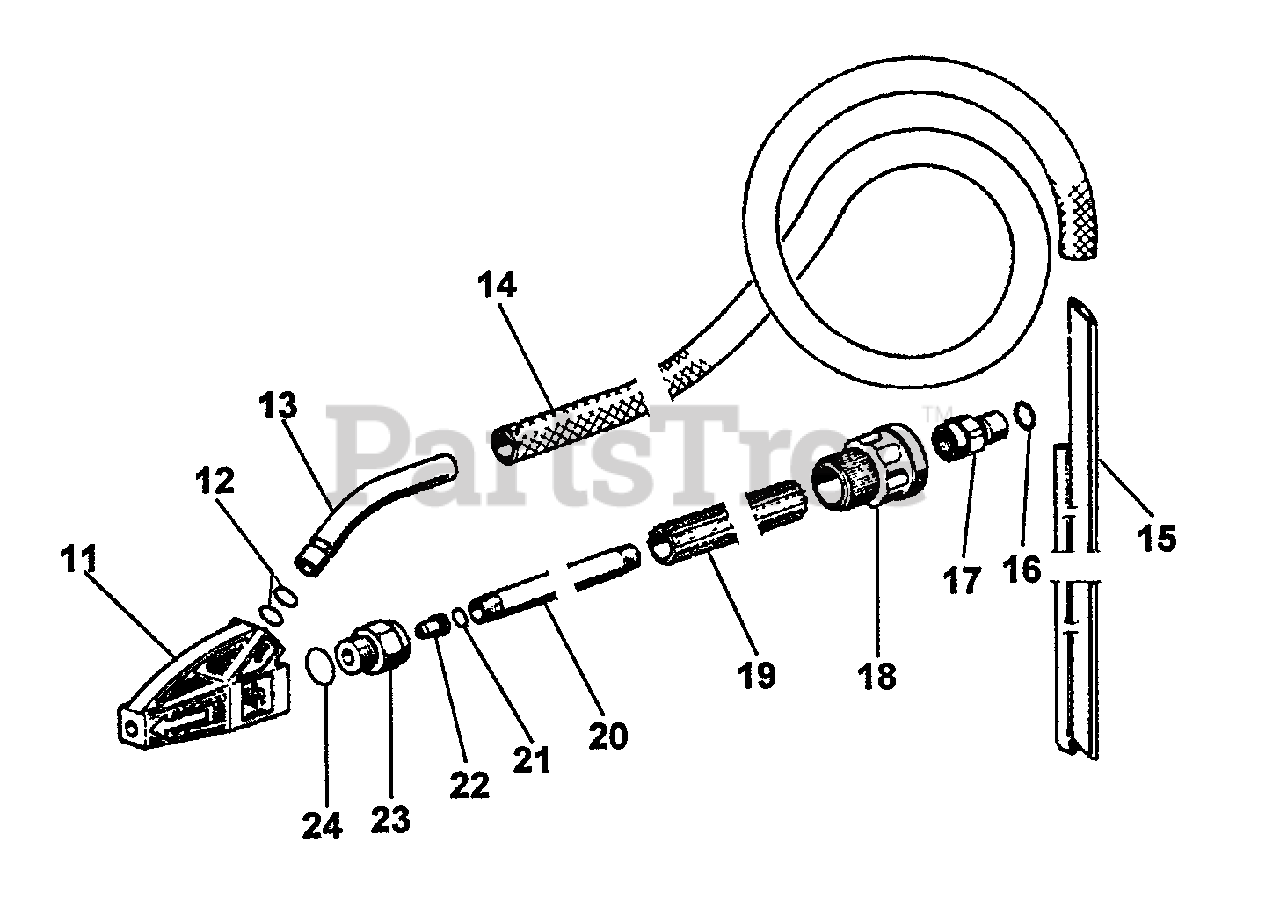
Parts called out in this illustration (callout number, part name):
11	NOZZLE, SAND
12	O-RING
13	CONNECTOR, SAND TUBE
14	TUBE, SAND
15	PROBE, SAND
16	O-RING - .359 X .103
17	COUPLING - MALE
18	RINGNUT
19	GRIP, HANDLE
20	TUBE
22	NOZZLE, SAND BLASTING
23	HOLDER, NOZZLE
24	O-RING - .614 X .070
